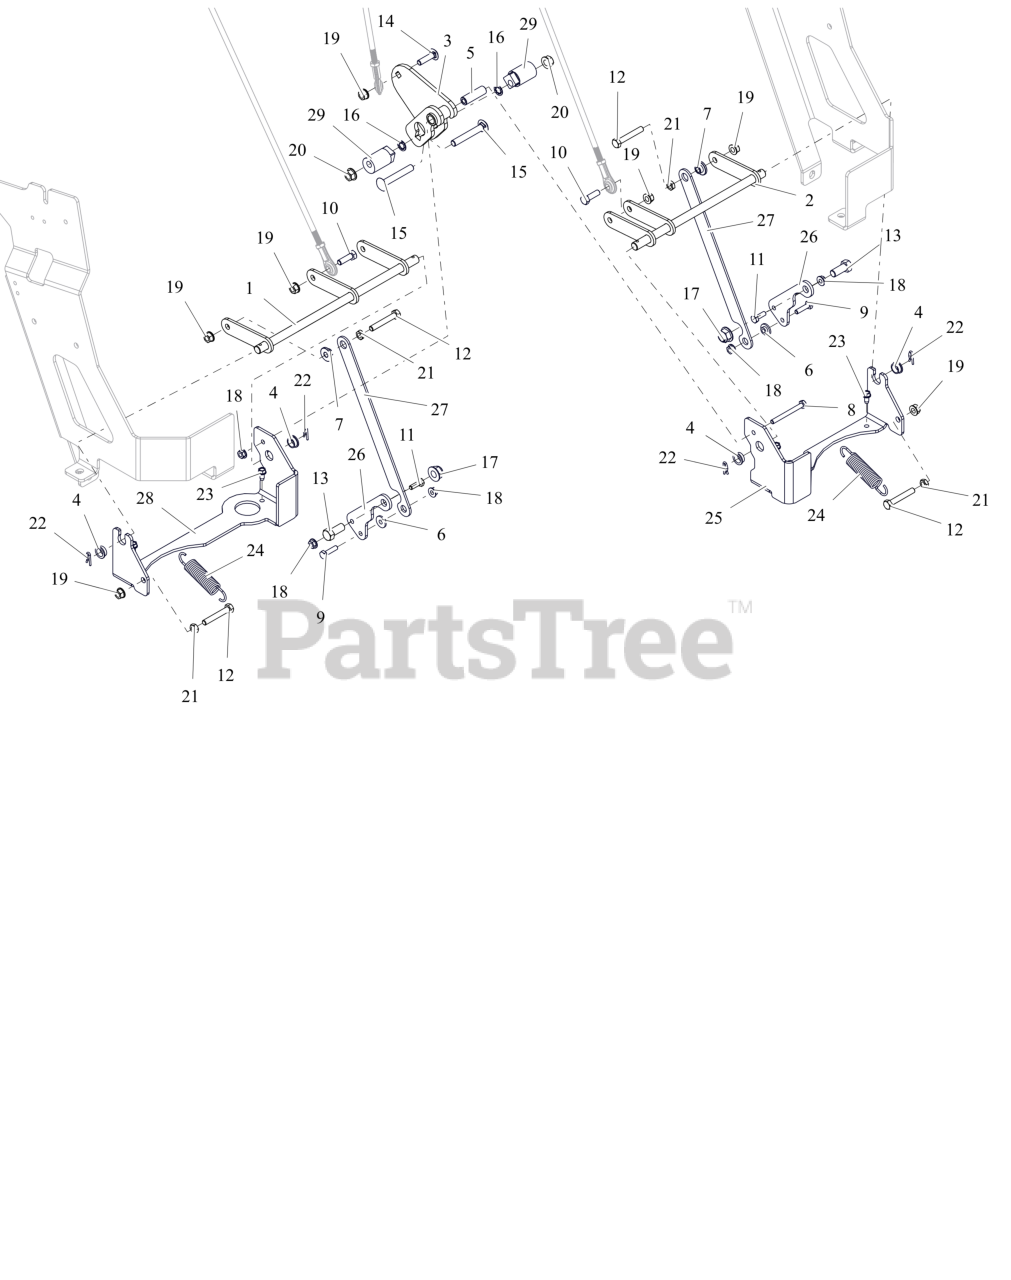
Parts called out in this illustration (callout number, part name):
1	WLDMT, RH LOWER STEERING SHAFT (BLACK)
2	WLDMT, LH LOWER STEERING SHAFT (BLACK)
3	WLDMT, SPEED STOP
4	BSHG,FLANGE .500X.625X.270X.75
5	BSHG, SLV .265X.505X1.665
6	BSHG-FLG .265X.437X.250X.750
7	BSHG-FLG .32X.500X.344X.880
8	BLT, HEX 0.25-20X2.5 GR8 ZCC
9	BLT,HEX .25-20X1.00 G5 ZCC
10	BLT,HEX .31-18X1.00 G5 ZCC
11	BLT, HEX .25-20X.75 G5 ZCC
12	BLT, HEX .31-18X2.00 G5 ZCC
13	BLT, HEX 0.4375-14X1 GR5 ZCC
14	BTL,RHSSN .313-18 X 1.25 G5 ZCC
15	BLT, RHSSN.38-16X2.50 G5 ZCC
16	WSHR-LK .38 INT STAR YWZC
17	NUT,NYL-FLG .44-14 GF ZCC
18	NUT-LK-CTR-FLG .25-20 ZC120
19	NUT,LK-CTR-FLG .31-18 GF ZCC
20	NUT-LK-CTR-FLG .375-16 GF ZCC
21	NUT-JAM .312-18 G2 ZCC
22	CLIP, SPRING
23	SCR-TAP .25-20X.50 HWH ZCC
24	SG-TENS .105X.812X3.88 WLD 15
25	BRKT, LOWER STEERING - LH
26	PLATE, TRANSAXLE ADAPTER (BLACK)
27	LINK, STEERING (BLACK)
28	BRKT, LOWER STEERING - RH
29	ECCENTRIC - .390X1.000X1.750
